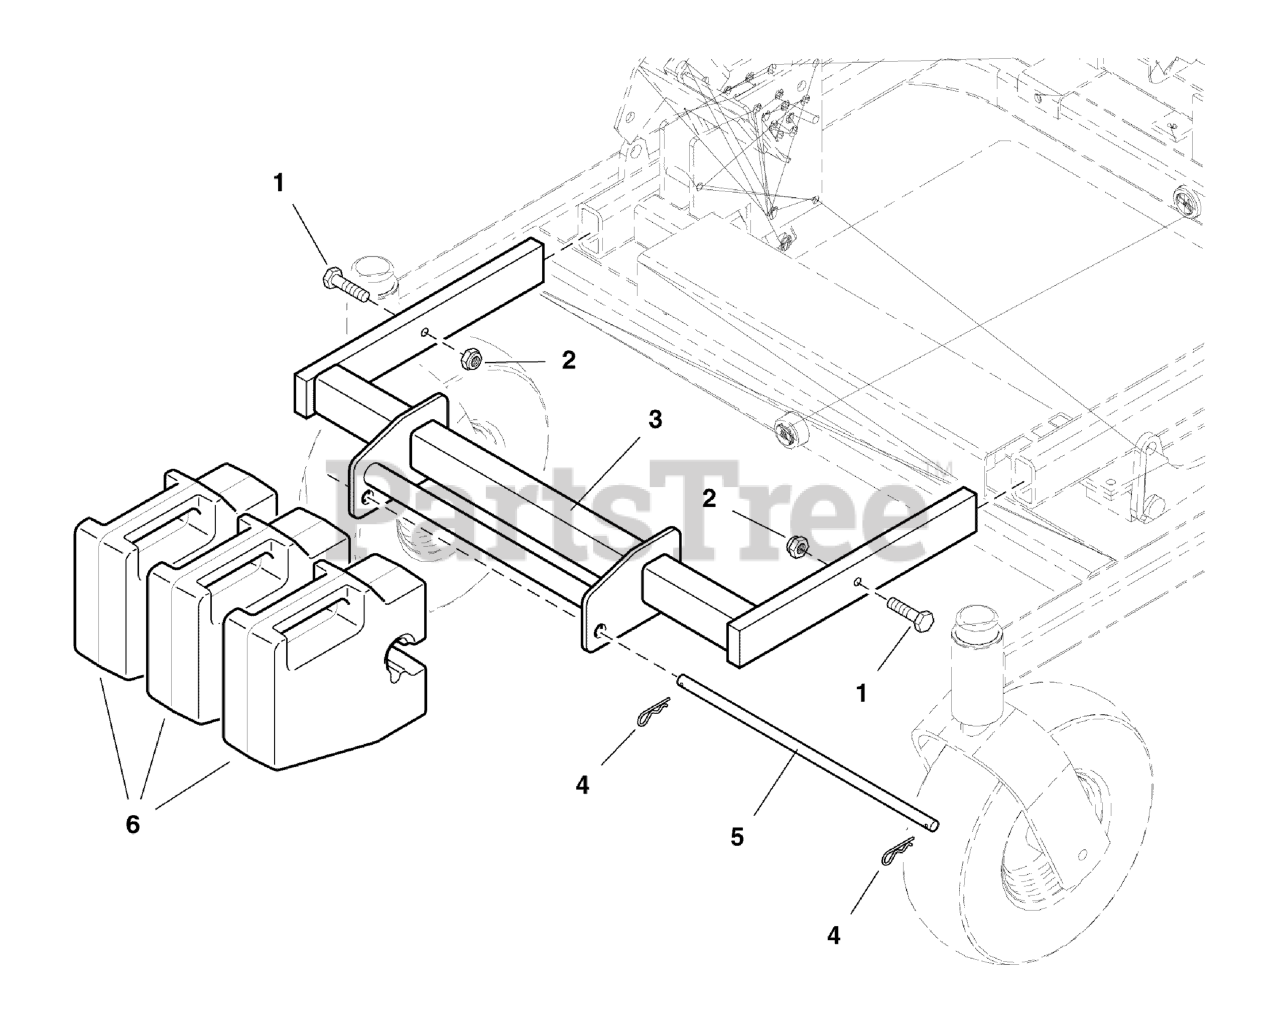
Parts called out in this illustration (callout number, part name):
1	BOLT, 3/8-16 X 2, GD5, CZ
2	NUT, 3/8-16 HEX NYLON LOCK
3	3-BAG WEIGHT RACK WELDMENT
4	PIN, HAIR, .0915 X 1-7/8
5	ROD, WEIGHT RETAINER
6	WEIGHT-QUICK ATTACH 50LB SUITCASE PAINTED
